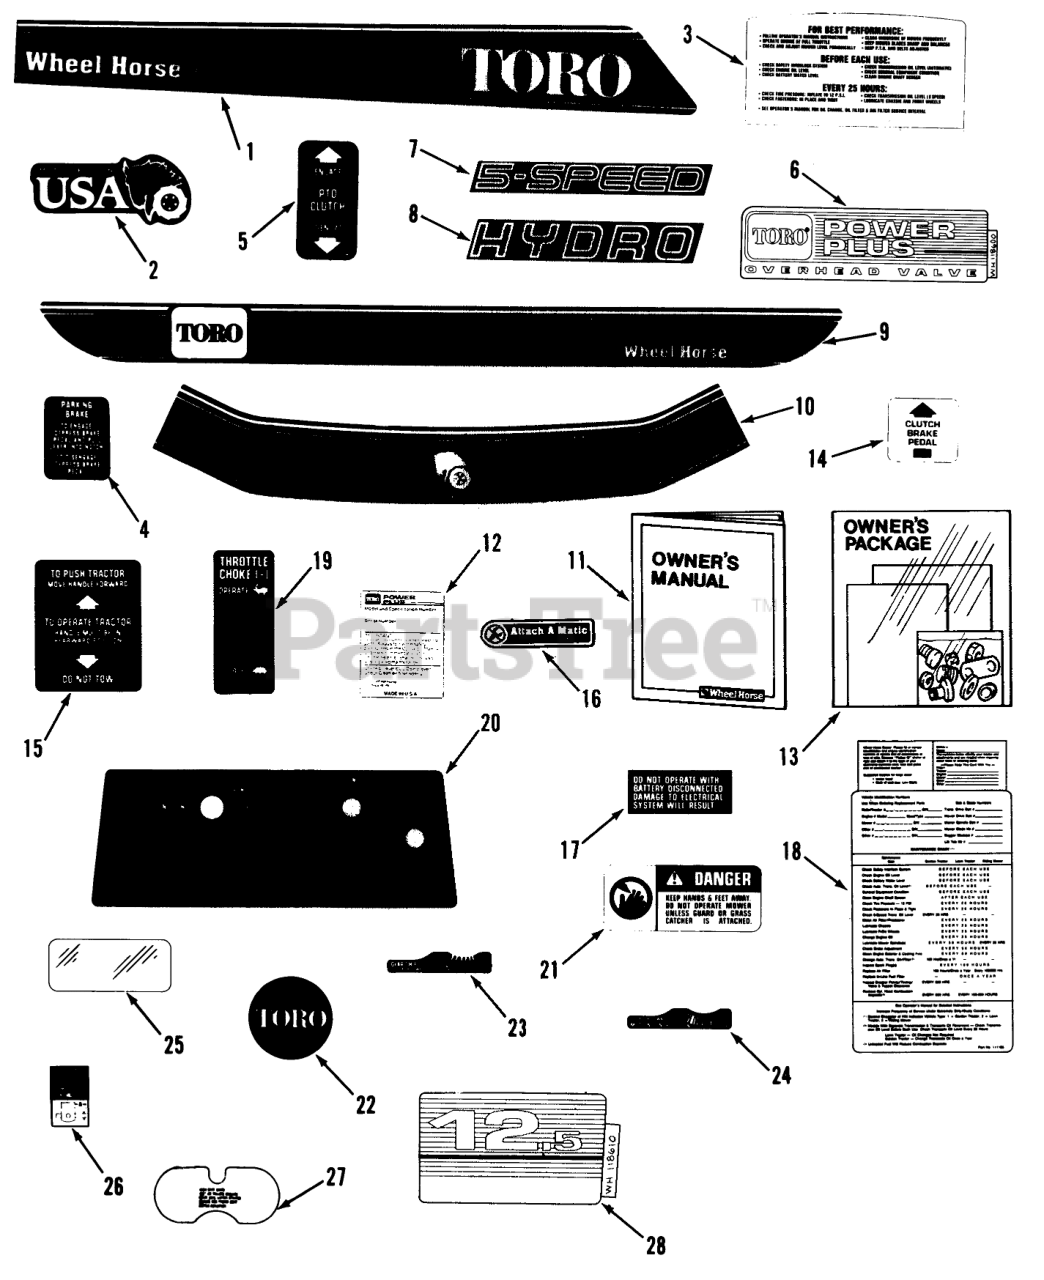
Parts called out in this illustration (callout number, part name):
1	DECAL-HOOD 210-5 R H
2	Decal-Made In USA
3	Decal-Hood Rear
4	DECAL PARKING BRAKE
5	DECAL-PTO
6	DECAL-PWR PLUS
7	DECAL-MODEL 5-SPEED
8	DECAL-MODEL HYDRO
9	DECAL-FENDER
10	DECAL-FRONT HOOD
11	Operator-s Manual 212-5
13	New Tractor Loose Parts Package 210-5
14	DECAL CLUTCH & BRAKE
15	DECAL-PUSH
16	Decal-Attach-A-Matic
17	DECAL ELECT SYSTEM
18	MAINTENANCE-DECAL
19	DECAL-THROTTLE
20	DECAL-BACK PLATE
21	DECAL-DANGER
22	DECAL-TORO ENGINE
23	DECAL-SHIFT 5-SPEED
24	Decal-Motion Control 210-H, 212-H
25	DECAL-OVERLAY
26	DECAL-PTO BELT ADJ
27	DECAL-SEAT LIFTER
28	DECAL-PWR PLUS 12.5
